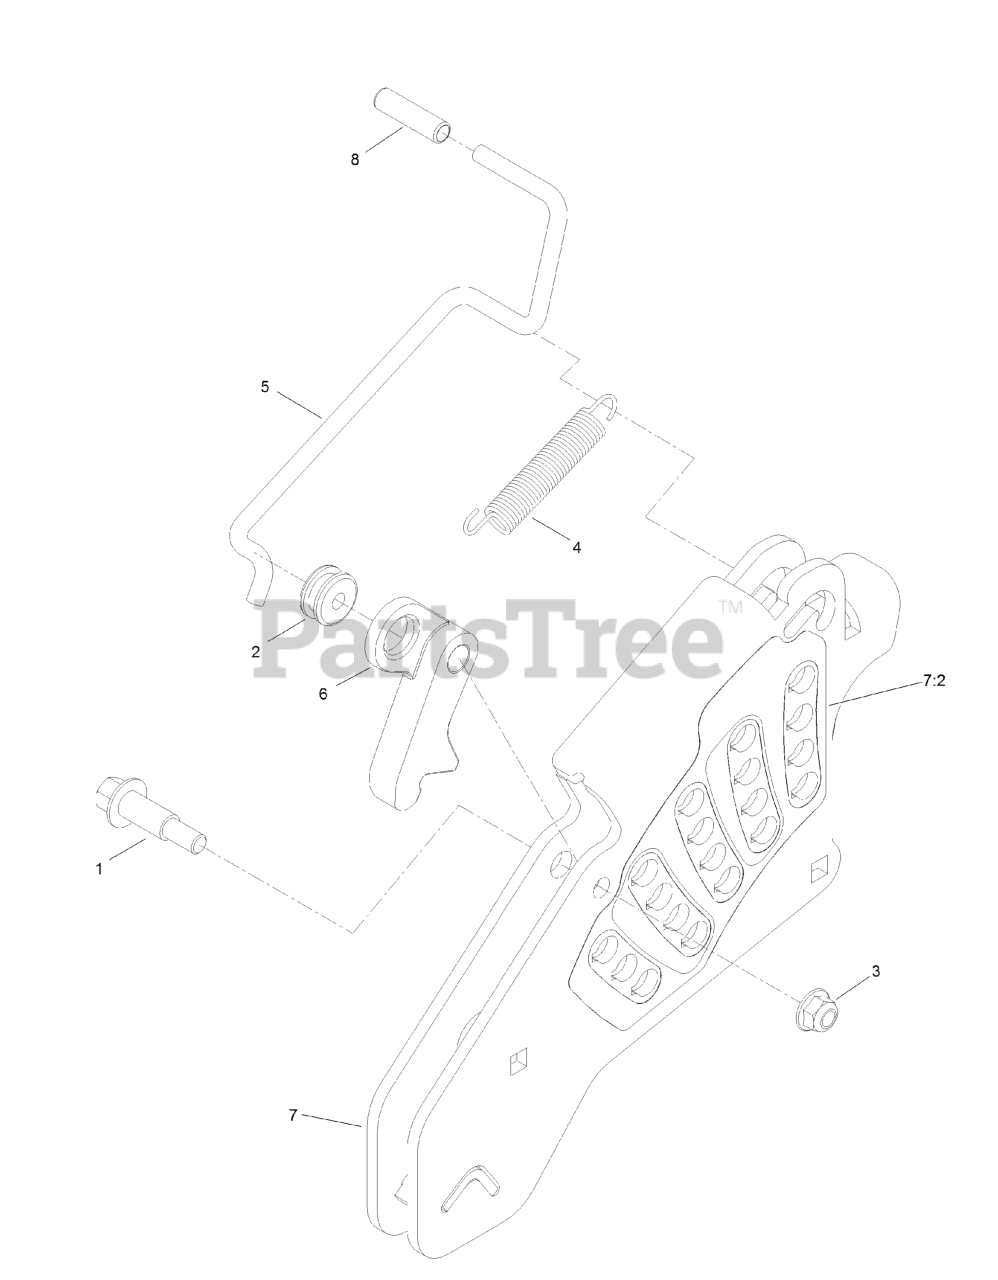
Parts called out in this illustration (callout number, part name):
1	BOLT-SHOULDER
2	GROMMET
3	NUT-HF, NI
4	SPRING-EXTENSION
5	ROD-LOCK, TRANSPORT
6	PAWL-TRANSPORT, HOC
7	HOC PLATE ASM
7:2	DECAL-HOC
8	GRIP-LEVER
